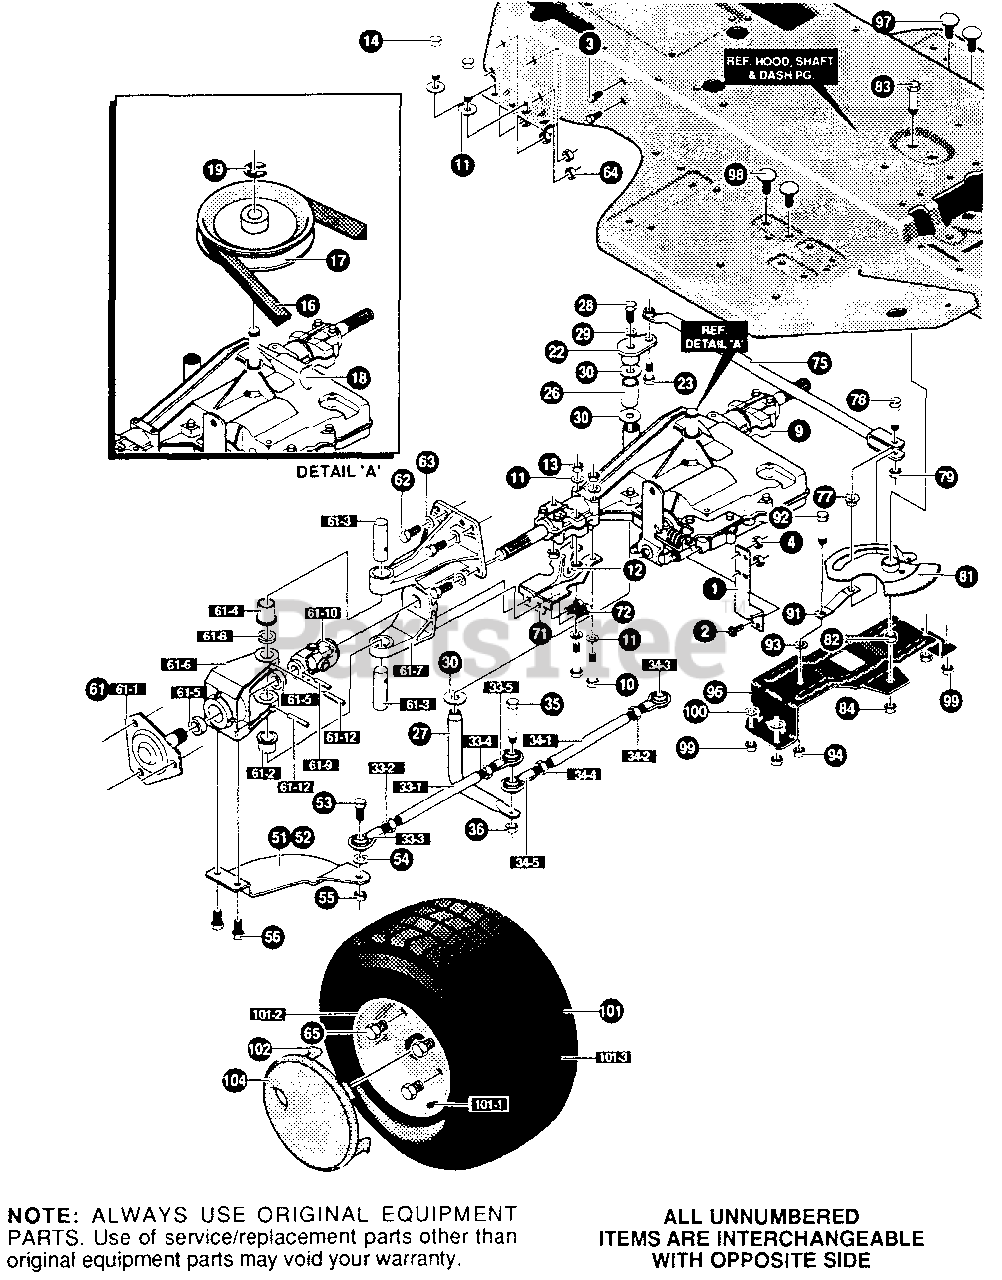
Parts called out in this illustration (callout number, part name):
1	BRACKET, STABILIZER EURO
2	SCREW, 5/16-18X .75 WAHHTAP
3	SCREW. 5/16-18X .75 HHC
4	NUT, 5/16-18 REGHEXCTRLK
10	SCREW, 5/16-18X2.50 HHC
11	WASHER, FLAT .344X .69X.065
12	NUT, 5/16-18 HWDFLCTRLK
13	NUT, 5/16-18 REGHEXCTRLK
14	SCREW, 5/16-18X2.50 HHC
16	BELT, V 4L 90.00 LG
17	PULLEY, 6.6 OD V4L T/A
18	KEY, HI-PRO 606 .75DIAX.187WD
19	RING, RETEX.58X.035TRU5100-62
22	PIVOT, STEERING
23	BOLT, .562X.340 HHSH 3/8-24
26	SPACER, STEERING SHAFT
27	SHAFT, STEERING PIVOT (ZN)
28	SCREW, 5/16-24X 1.00 HHC
29	WASHER, FLAT .333X .87X.119
30	WASHER, FLAT .765X1.19X.048
33	TIE ROD, ASSYRH EURO 4WS &LF STD
33-1	ROD, TIE 1/2"D X 8.12LG
33-2	NUT, 3/8-24 LH THD REGHJAM
33-3	BALL JOINT LH 3/8-24
33-4	NUT, 3/8-24 REGHEXJAM
33-5	BALL JOINT,RH 3/8-24
34	TIE ROD, ASSYLH EURO 4WS & LF STD
34-1	ROD, TIE 1/2"D X 9.75LG
34-2	NUT, 3/8-24 LH THD REGHJAM
34-3	BALL JOINT LH 3/8-24
34-4	NUT, 3/8-24 REGHEXJAM
34-5	BALL JOINT,RH 3/8-24
35	SCREW, 3/8-24X1.75 HHC
36	NUT, 3/8-24 HXCTRLK
51	ARM REAR WHL STR (FER) R.H. 1
52	ARM, REAR WHEEL STEER L.H
53	SCREW, 3/8-24X1.25 HHC
54	WASHER. REGSPTLK.393X.68X.10
55	NUT, 3/8-24 HXCTRLK
56	SCREW, 3/8-16X1.00 WAHHTAP
61	U-JOINT, ASS'Y 4-WS LT DUTY
61-1	HUB ASSEMBLY
61-2	BEARING, FLSH .752IDX .937ODX.75
61-3	PIN, STEERING HINGE
61-4	BEARING. FLSH IDX ODX
61-5	BEARING. BALL 6203-2AA-3/4
61-6	BRACKET, STEERING PIVOT
61-7	BRACKET, STR PIVOT
61-8	WASHER, FLAT .765X1.25X.042PL
61-9	PIN, GROOVED .250 DIAX1.50LG
61-10	U-JOINT ASSEMBLY W/ZERK (LONG)
61-12	PIN, SPRING.250DIAX1.50LG HVPL
62	SCREW, 5/16-18X1.00 HHC
63	WASHER, FLAT .344X .69X.065
64	NUT, 5/16-18 REGHEXCTRLK
65	SCREW, 1/2-20X .50 HHC
71	BRACKET X-AXLE MTG 4WS
72	SCREW, 5/16-18X .75 WAHHTAP
75	ROD R WHL STR 4WS(930-6)
77	CAM YOKE ROLLER
78	BOLT, .625 X1.175HHSH
79	NUT, 1/2-20 REGHXCTRLK
81	ASSY SECTOR GEAR 4WS
82	BEARING, SLEV. IDX. ODX
83	SCREW, 1/2-20X2.50 HHC
84	NUT, 1/2-20 REGHXCTRLK
91	FOLLOWER, ROLLER
92	BOLT, .265X .800 HHSH 3/8-24
93	WASHER. FLAT .375X .88X.082
94	NUT, 3/8-24 HXCTRLK
96	PLATE, PIVOT STEERING EURO
97	SCREW, 5/16-18X .50 WAHHTAP
98	SCREW, 5/16-18X .75 WAHHTAP
99	NUT, 5/16-18 REGHEXCTRLK
100	WASHER, FLAT .375X .88X.082
101	TIRE & RIM,20X10.00-8 TURF 661
101	VALVE STEM
101	RIM, WHEEL
101	TIRE, 20X10.00-8
102	CLIP, HUBCAP TINN #C25467-017-4
104	HUB CAP, 8" EURO
